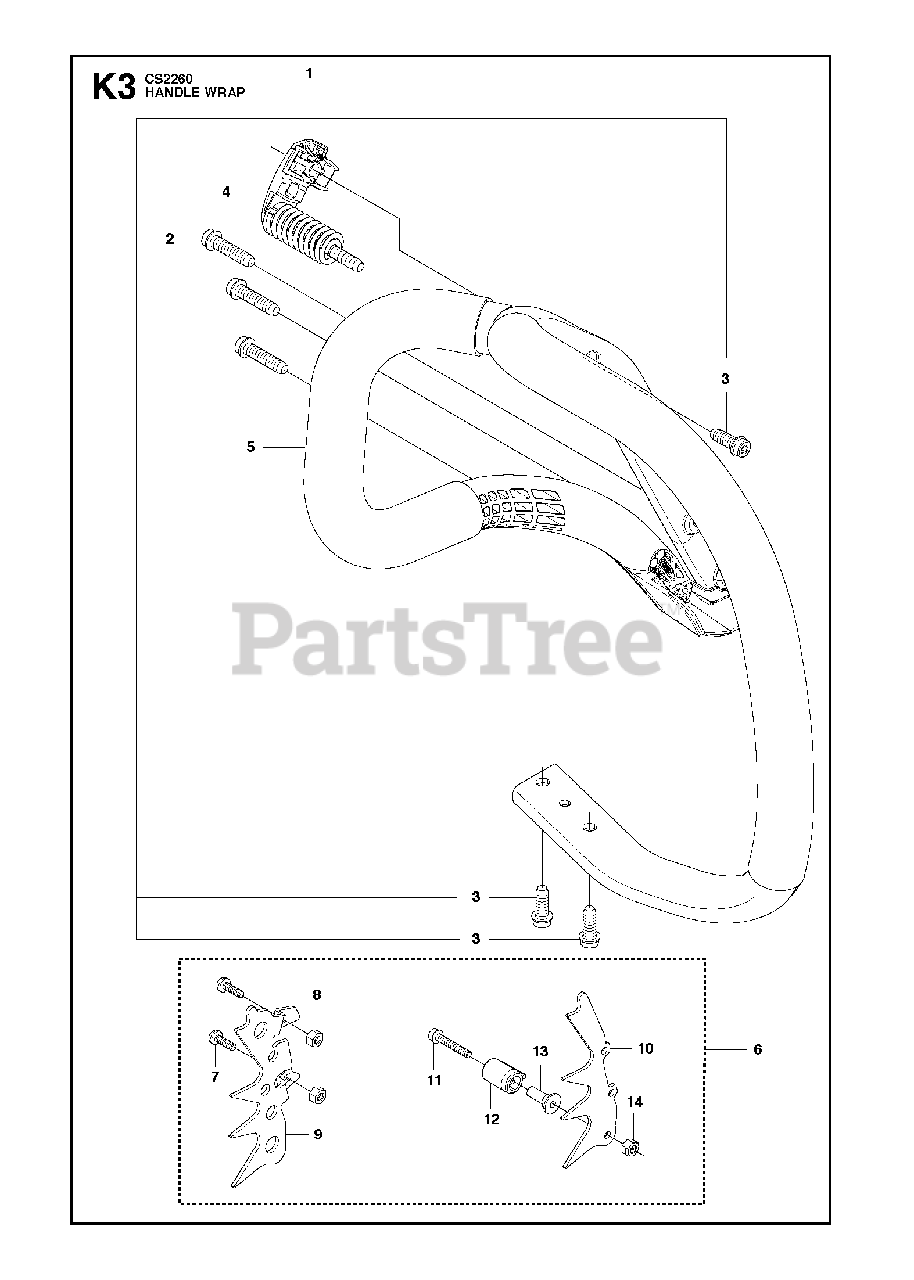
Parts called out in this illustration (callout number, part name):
1	ENCLOSED KIT
2	SCREW
3	SCREW IHSCFT
4	ANTIVIBRATION ELEMENT
5	HANDLE WRAP
7	SCREW
8	NUT
9	SPIKE, OUTER
10	SPIKES, INNER
11	SCREW IHSCFM
12	SPACER
13	CHAIN CATCHER
14	NUT
